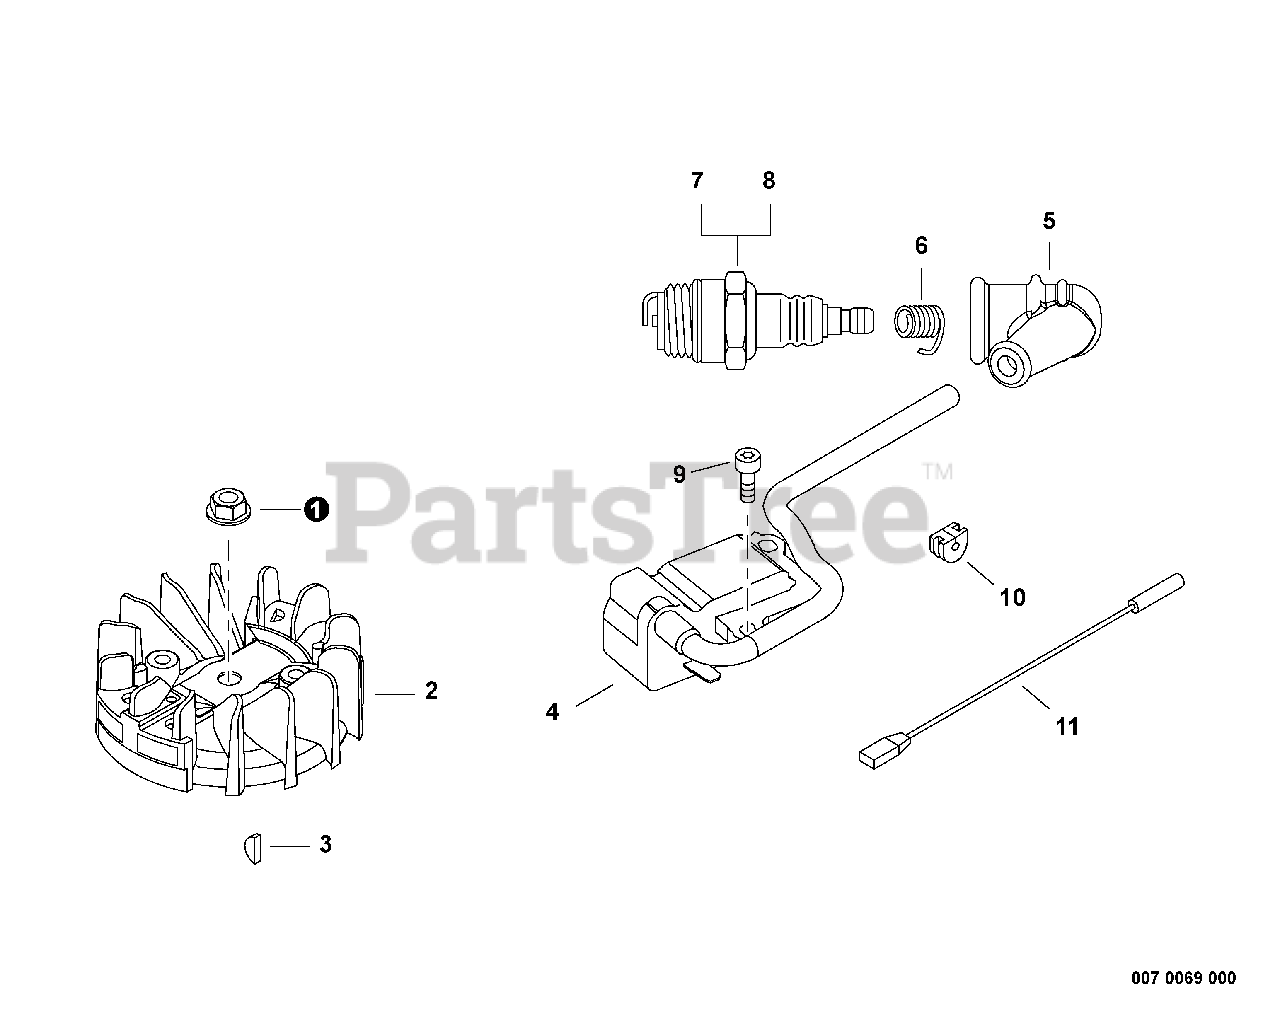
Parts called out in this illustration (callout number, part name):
1	NUT - FLANGE
2	FLYWHEEL
4	COIL, IGNITION
5	CAP, SPARK PLUG
6	TERMINAL, SPARK PLUG CAP
7	SPARK PLUG -- BPM-8Y
8	SPARK PLUG -- BPMR-8Y
9	SCREW - 4
11	LEAD - IGNITION
